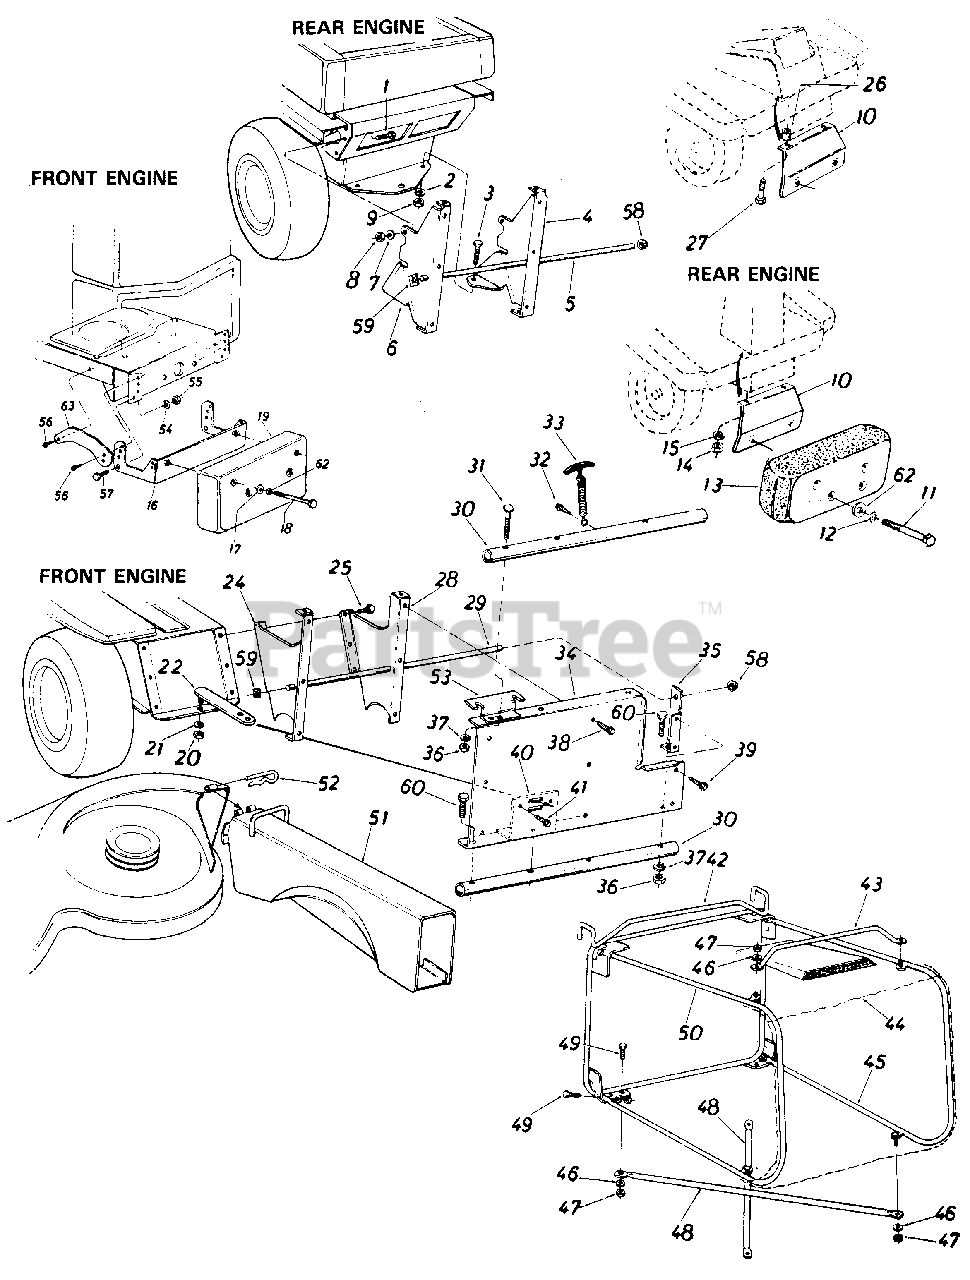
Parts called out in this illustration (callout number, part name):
1	Hex Bolt 5/16-18 x 1.00" Lg. *
2	L.Wash.5/16" I.D.*
3	Hex Bolt 5/16-18 x 1.00" Lg.*
4	Catcher Support Brkt-R.H.
7	L.Wash. 5/16" I.D.*
8	Hex Nut 5/16-18 Thd.*
9	Hex Nut 5/16-18 Thd.*
10	Counterweight Bracket
11	Hex Bolt 3/8-16 x 4.5" Lg.*
12	Belleville Wash..400" I.D. x .88" O.D.
13	Front Counterweight 381bs.
14	Hex Nut 5/16-18Thd.*
15	L.Wash. 5/16" I.D.*
16	Counterweight Bracket
17	BellevilleWash..400" I.D. x .88" O.D.
18	Hex Bolt 3/8-16 x 4.5" Lg. *
19	Front Counterweight 38 Ibs.
20	Hex Jam Nut 1/2-13 Thd.*
21	L.Wash. 1/2" I.D.*
25	Hex Wash. Hd. Self Tap Scr. 5/16-18 x .75 Lg.*
26	Spacer.380" I.D. x 1.00" O.D. x .320" Lg.
27	Not Part of Kit
28	Catcher Support Brk't. R. H.
31	Curved Carriage Bolt 5/16-18 x 1.75" Lg.
32	Hex AB-TapScr. 1/4 x .62" Lg.
33	Hood Latch Ass'y.
34	Grass Catcher Adapter
35	Grass Catcher Support Brk't.-R.H.
36	Hex Nut 5/16-18 Thd.
37	L.Wash.5/16" I.D.
38	Hex Wash. Hd. Self Tap Scr. 1/4-20 x .50" Lg.
39	Hex Wash. Hd. Self Tap Scr. 1/4-20 x .50" Lg.
40	Hitch Bracket
41	Hex Wash. Hd. Self Tap Scr. 1/4-20 x .50" Lg.
42	Grass Bag Frame Ass'y.
43	Grass Catcher Handle 26.75
44	Grass Catcher Bag
47	Hex L.Nut 1/4-20Thd.
48	Botom Cross Brace 30.36" Lg.
49	Hex Bolt 1/4-20 x .62" Lg.*
50	Catcher Side Frame Ass'y.-L.H .
51	Chute Extension Ass'y.
52	Not Part of Kit
53	Grass Catcher Support Plate
54	L.Wash. 7/16" I.D.
55	Hex Nut 7/16-20 Thd.
56	Hex AB Tap Scr. 5/16-18 x 1" Lg.
57	Hex Bolt 7/16-20x 1.00" Lg.*
58	Push Cap
59	Speed Nut
60	Hex Bolt 5/16-18 x 1.75" Lg.*
62	Fl.Wash. .390" I.D. x 1.12" O.D. x .187 Thk.
63	Tie Strap
